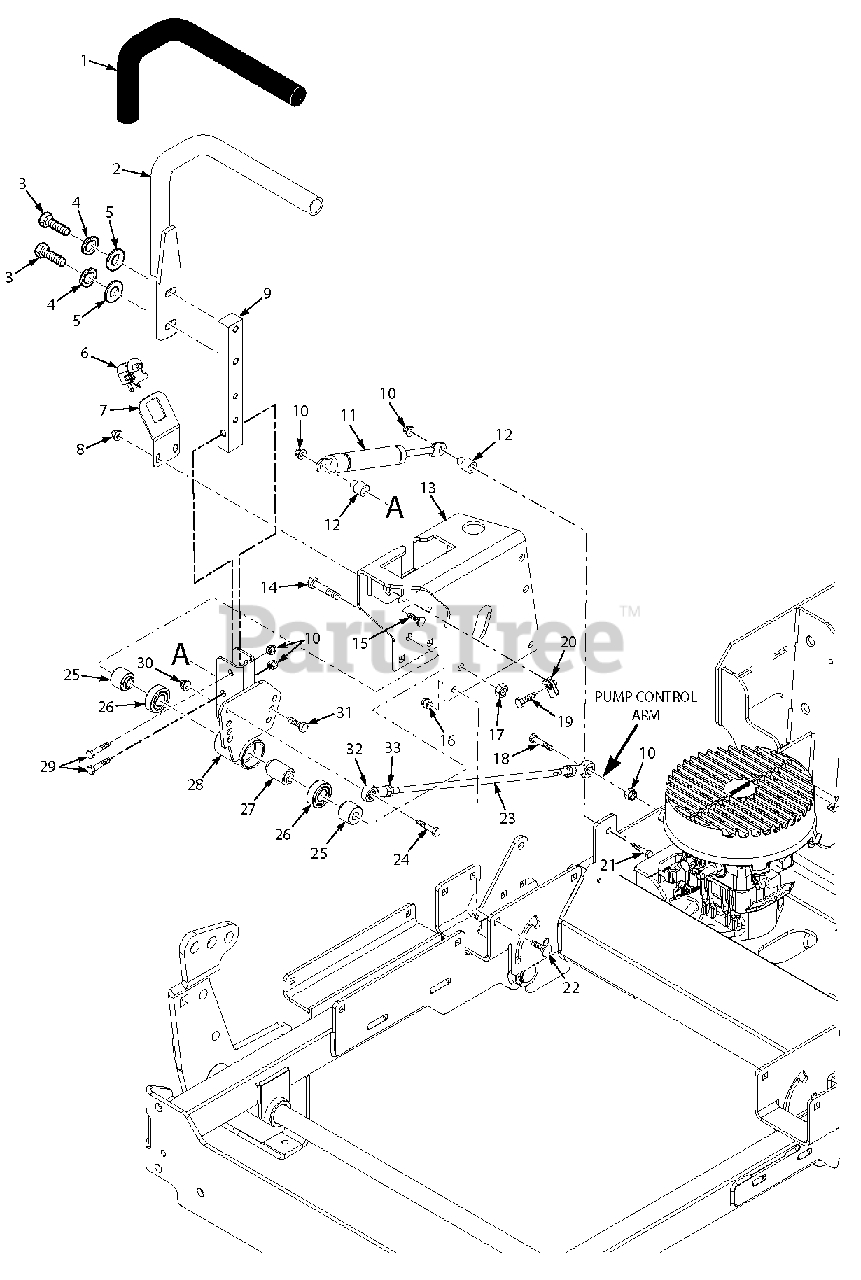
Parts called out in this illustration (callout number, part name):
1	Grip, Control Handle
2	Handle Bar w/Grip
3	Bolt, Hex Head 3/8-16 x 1-1/4"
4	Lockwasher, 3/8" Spring
5	Flatwasher, 3/8-.391 x .938 x .105
6	Switch, N/O
7	Bracket, Operator Presence Switch
8	Nut, Flanged Elastic Stop 1/4-20
9	Bar, Control Lever
10	Nut, Elastic Stop 5/16-18
11	Gas Damper
12	Spacer, Pump Dampener
13	Bracket Weldment, Control Lever RH w/Decal
13	Bracket Weldment, Control Lever LH w/Decal
14	Bolt, Hex Head 3/8-16 x 4-1/4"
15	Bolt, Carriage 1/4-20 x 3/4"
16	Nut, Serrated Flange 5/16-18
17	Nut, Center Lock 3/8-16
18	Bolt, Hex Head 5/16-18 x 1"
19	Bolt, Hex Head 3/8-16 x 1-1/4" with Thread Lock Patch
20	U-Nut, 3/8-16
21	Bolt, Hex Head 5/16-18 x 1-1/2", RH
21	Bolt, Hex Head 5/16-18 x 1-3/4", LH
22	Bolt, Carriage 5/16-18 x 3/4"
23	Linkage Assy, Steering
23	Rod End, 5/16-24 LH
23	Nut, 5/16-24 UNF Jam
24	Bolt, Hex Head 1/4-20 x 1-1/2"
25	Spacer, Controls
26	Bearing
27	Spacer, Bearing
28	Pivot Weldment, Control Arm RH
28	Pivot Weldment, Control Arm LH
29	Bolt, Hex Head 5/16-18 x 1-3/4"
30	Nut, Elastic Stop 1/4-20
31	Bolt, Hex Head 5/16-18 x 1-1/2"
32	Rod End, 5/16-24 RH
33	Nut, 5/16-24 UNF LH Jam
